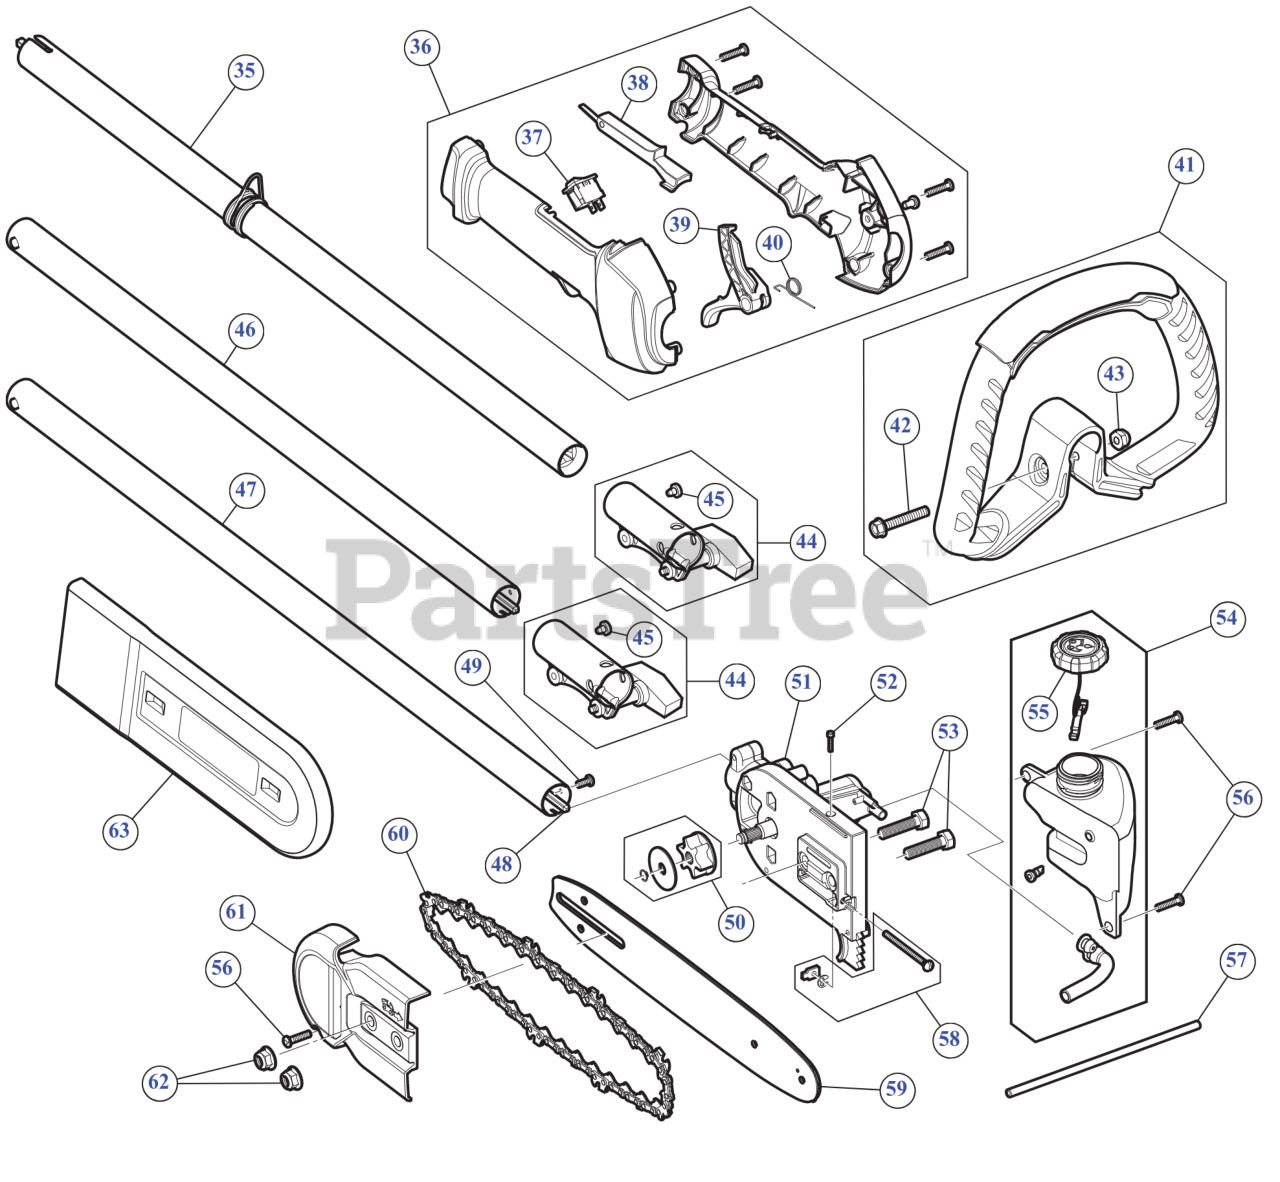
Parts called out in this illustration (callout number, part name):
35	UPPER SHAFT HOUSING
36	THROTTLE GRIP ASSEMBLY
37	SW, MOMENTARY ON/O
38	LEVER LOCK OUT
39	THROTTLE TRIGGER
40	TRIGGER SPRING
41	HANDLE DLX
42	BOLT 1/4-20X1 1/2
43	NUT 1/4-20 NYLOC
44	COUPLER ASSEMBLY
45	SCREW, 10-32X.250 TA
46	EXTENSION BOOM
47	LOWER SHAFT HOUSING
48	FLEXIBLE DRIVE SHAFT
49	SCREW 1/4-20 X.500
50	SPROCKET ASSEMBLY
51	GEAR BOX ASSEMBLY
52	SCREW 4X40X.50
53	SCREW 5/16-18 x 1.25 GR5
54	OIL TANK
55	OIL CAP
56	SCREW, #8-16X.750 PH
57	OIL LINE
58	CHAIN TENSION HDW
59	BAR 10"
60	CHAIN 10"
61	CHAIN GUARD
62	FLANGE LOCK NUT 5/16-18
63	SCABBARD
